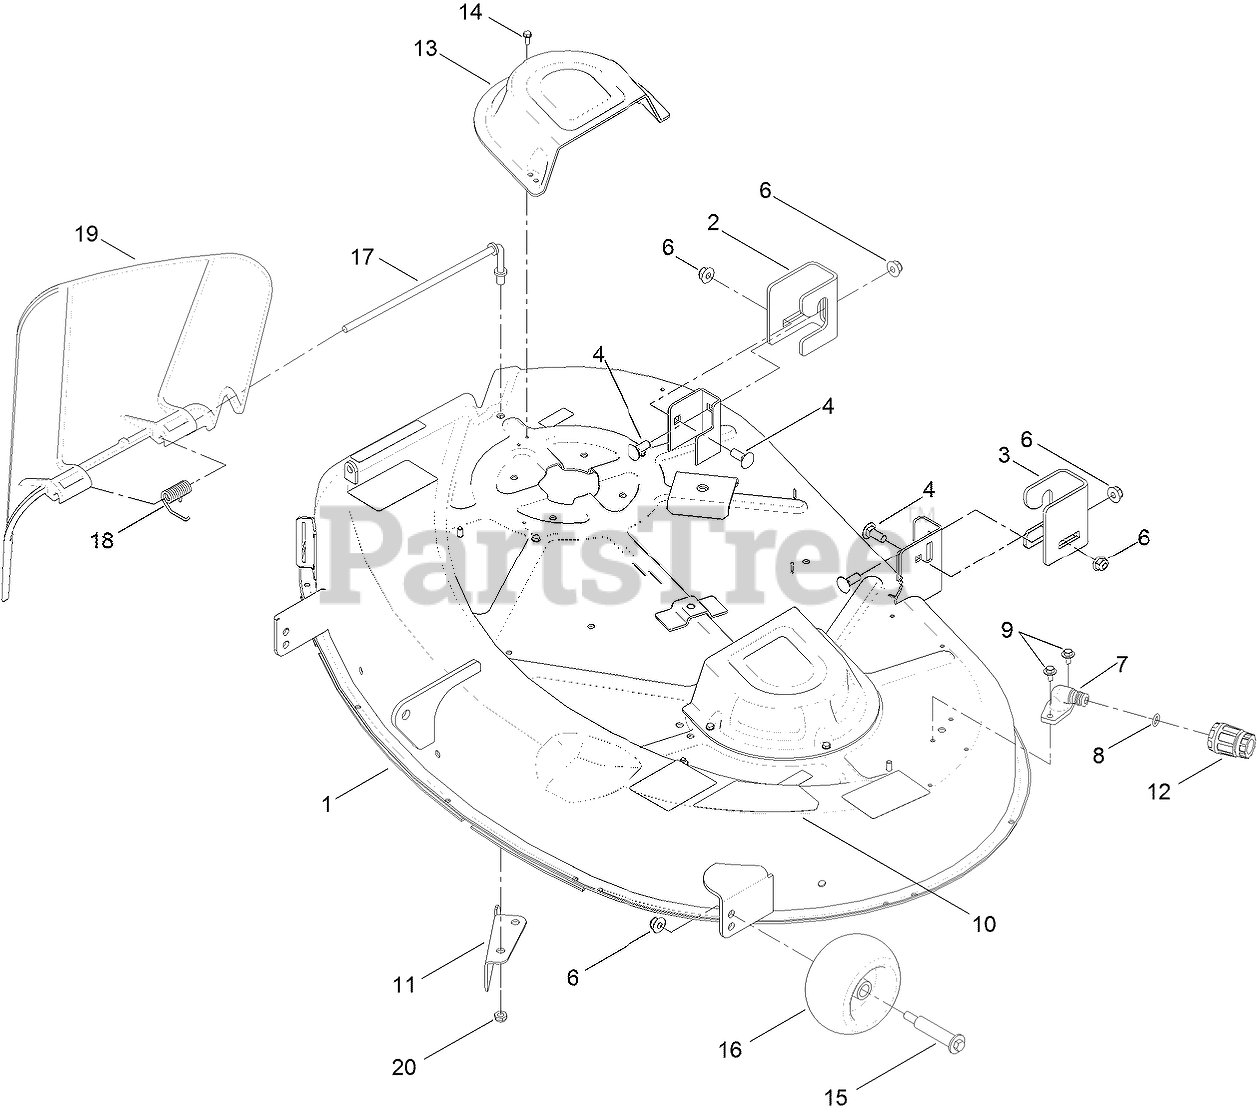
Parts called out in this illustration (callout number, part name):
1	42 INCH DECK AND DECAL ASM
2	BRACKET-HANGER, RH
3	BRACKET-HANGER, LH
4	BOLT-CARR
6	NUT-HF, NI
7	FITTING-WASHOUT
8	O-RING
9	SCREW-HHFTF
11	BAFFLE-CUTOFF
12	CONNECTOR-HOSE
13	COVER-BELT
14	SCREW-TAPTITE
15	BOLT-SHOULDER
16	ROLLER-SCALP, ANTI
17	ROD-PIVOT
18	SPRING-TORSION
19	DEFLECTOR
20	NUT-LOCK, NI
